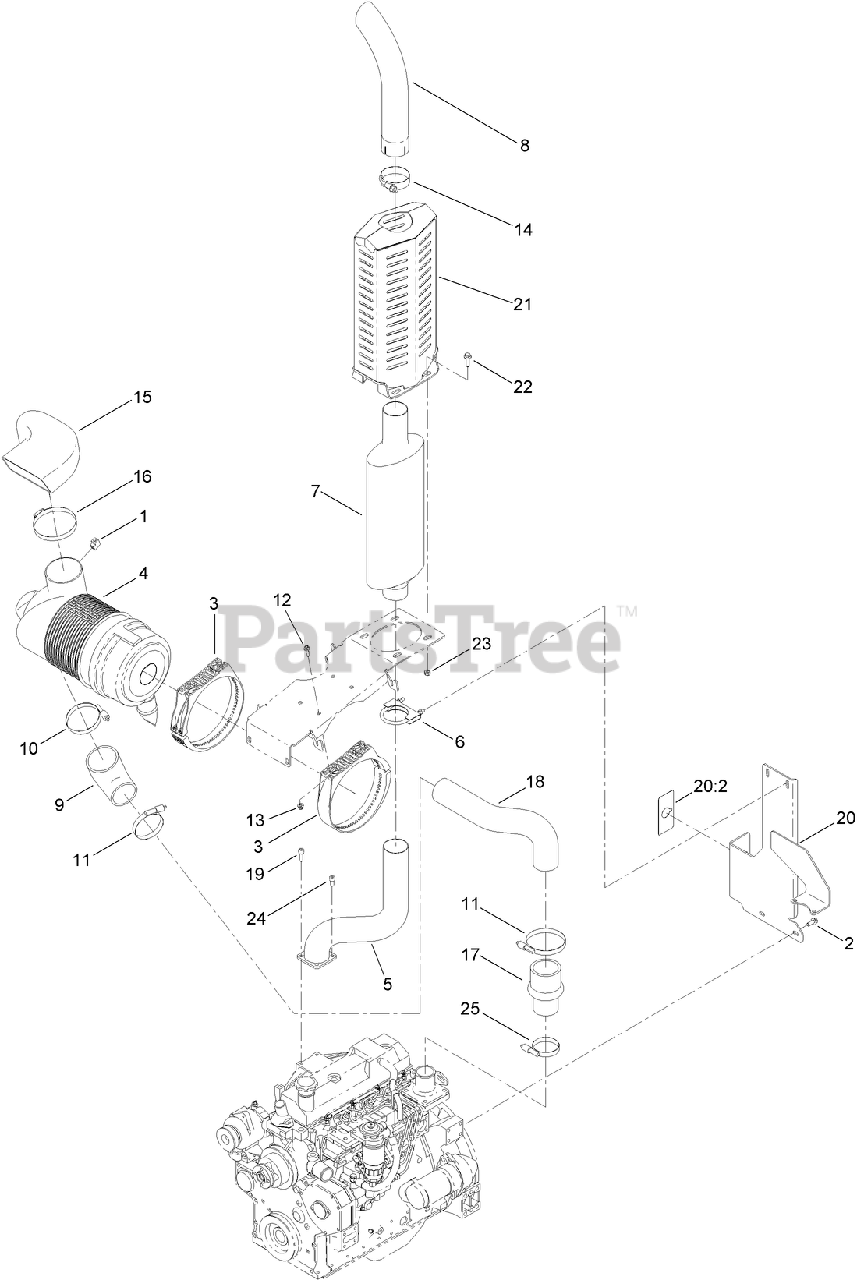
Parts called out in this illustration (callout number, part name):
1	FITTING-ELBOW, 90
2	SCREW-HHF
3	BAND-MOUNTING, AIR CLEANER
4	AIR CLEANER ASM
5	TUBE-EXHAUST
6	BOLT-U, CLAMP
7	MUFFLER-VERTICAL, OVAL
8	EXHAUST-STACK
9	CONNECTOR-AIR INTAKE
10	CLAMP-TORQUE, CONSTANT
11	CLAMP-TORQUE, CONSTANT
12	SCREW-HHF
13	NUT-LOCK, HHF
14	CLAMP-MUFFLER
15	INTAKE-Air
16	CLAMP-HOSE, WORM GEAR (HEAVY DUTY)
17	CONNECTOR-Air Intake
18	TUBE-Air Intake
19	SCREW-HSH
20	MUFFLER SUPPORT MOUNT ASM
20:2	DECAL-BATTERY DISCONNECT
21	SHIELD-EXHAUST
22	SCREW-HHF
23	NUT-LOCK, NI
24	SCREW-HSH
25	CLAMP-HOSE
